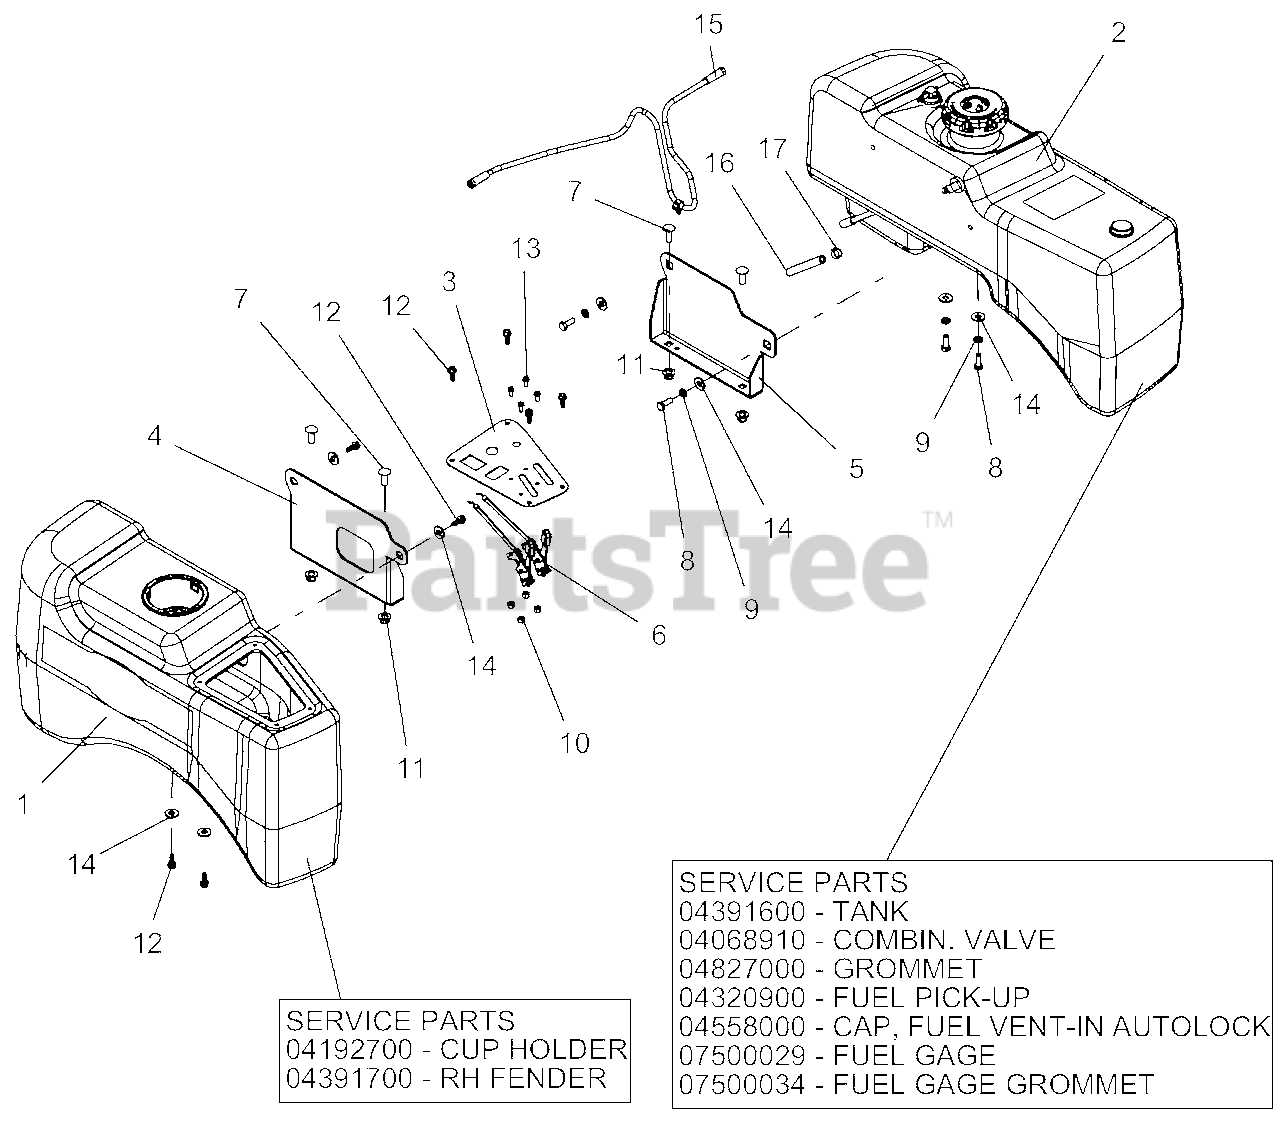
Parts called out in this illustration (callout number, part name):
1	ASM, FENDER W/CUPHOLDER
1	CUP HOLDER
1	RH FENDER
2	HD, FUEL TANK ASSEMBLY
2	TANK
2	COMBIN. VALVE
2	FUEL PICK-UP
2	CAP, FUEL VENT-IN AUTOLOCK
2	FUEL GAGE
2	FUEL GAGE GROMMET
3	PANEL, INSTRUMENT-BLACK
4	BRKT, RH HD FUEL TANK MTG-RED
5	BRKT, LH HD FUEL TANK MTG-RED
6	CABLE, CONTROL
7	BLT-RDHDSHSQNK.38-16X1.0 G5YZ
8	BLT-HEX .31-18X.875 GR5 YWZC
9	WSHR-LK .31X.078 REG YWZC
10	NUT-LK-NYL #10-24 YWZC
11	NUT-LK-NYL-FLG .38-16 YWZC
12	SCR-PLASTITE .25-10X.75 YWZC
13	@SCR-MCH 10-24X.50 HWH YWZC
14	WSHR-FL-STL.38X.875X.083 YWZC
15	KAWASAKI, VENT LINE HD/PRO-TURN
16	.25 LOW-PERM GAS HOSE 18.50" LG - TANK TO ENGINE
17	CLAMP, FUEL LINE
